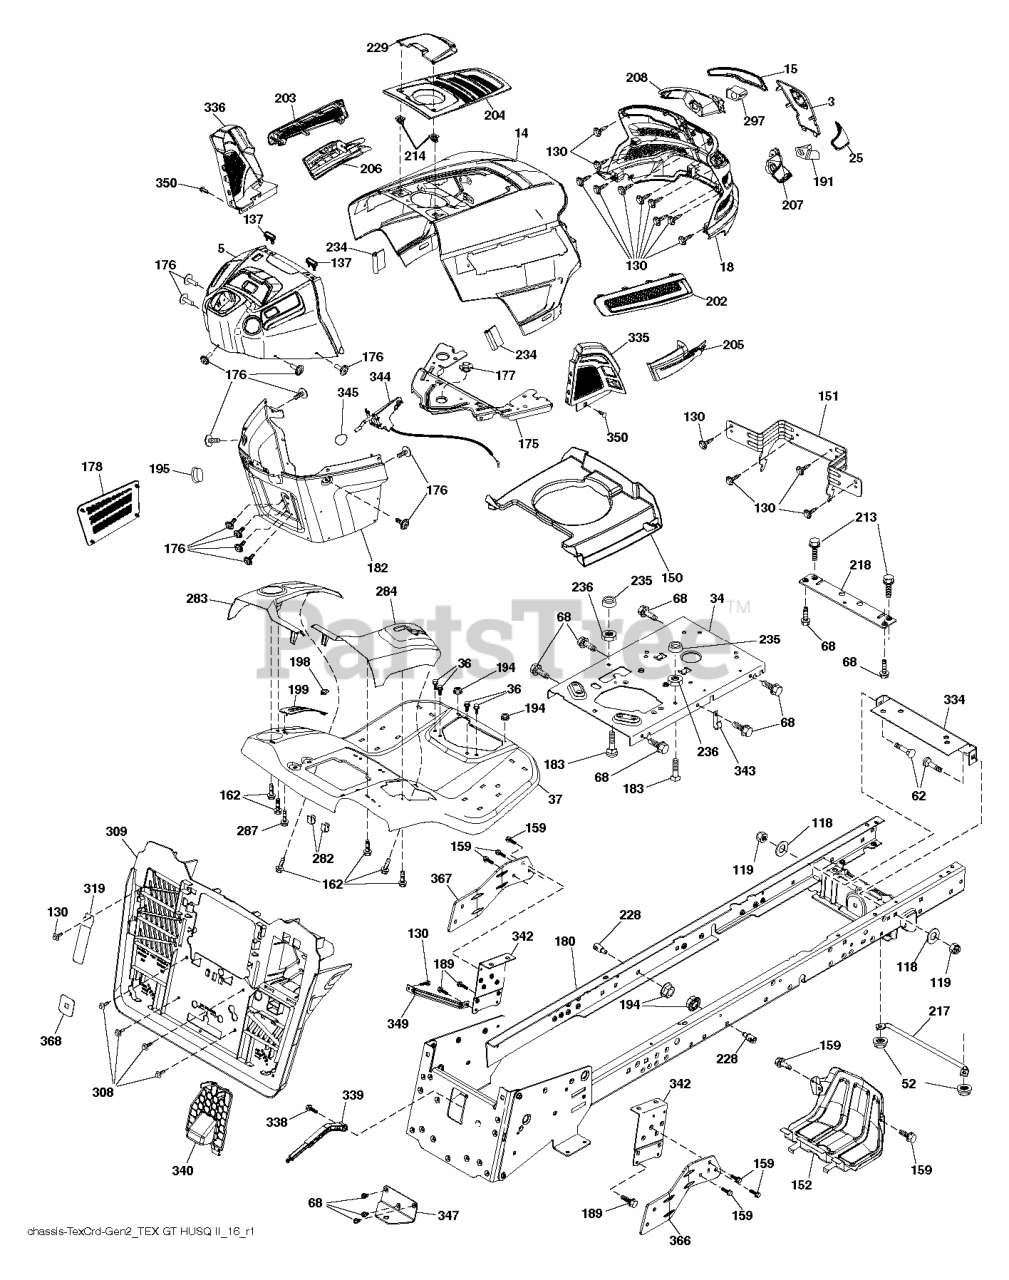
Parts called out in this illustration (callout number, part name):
3	APPLIQUE.SUBASM.GT.HUSQ.II
14	HOOD.ASM.HUSQVARNA.GT.TEX.ORAN
15	LENS.HEADLIGHT.LH.GTII.2011
18	GRILLE.SUBASM.GT.HUSQ.II
25	LENS.HEADLIGHT.RH.GTII.2011
34	PLATE.ENGINE.10GA.CRD.GENII
36	SCREW 5/16"
37	FENDER.TEX.SRD.CRD.FRN.GUARDS
52	LOCKNUT
62	BOLT D
68	SCREW LT
118	WASHER
130	SCREW.#10 X 0.750.BOS
137	BUMPER DASH
150	AIR.DUCT.GTV.BLACK
151	BRACKET.PIVOT.HOOD.GT.HUSQ.II
152	SHIELD.BROWNING.PNT.GT.V2
159	SCREW, 3/8-16X3/4
162	SCREW.HI-LO.CONSOLE
175	PLATE.CROSSMEMBER.HUSQ
176	SCREW.#10-24X5/8.RN.QU
177	BUSHING, STEERING
178	CARGO.ASM.NET.TXGT.W/C
180	WELDMENT.CHASSIS.TEX.CRD.GEN.2
182	DASH DASH LOWER
183	BOLT.5/16-18X1-1/4 FULL THD
189	SCREW
191	INSERT.REFLECTIVE.RH.HUSQ.GTII
194	NUT LOCK HEX FLANGE 5/16-18
195	PLUG.HOLE.DASH.LOWER.12V.BLK
198	INDICATOR.DECK.LIFT.RED
199	PLATE DECK LIFT
202	VENT.SIDE.RH.GT.HUSQ.II.
203	VENT.SIDE.LH.GT.HUSQ.II.498
204	VENT.TOP.EXTERNAL.FILL.GT2.GRE
205	SIDE.TRIM.RH.GT.HUSQ.II
206	SIDE.TRIM.LH.GT.HUSQ.II.GRAY
207	BEZEL LIGHT.RH.GT.II.MYLAR
208	BEZEL LIGHT.LH.GT.II.MYLAR
213	BOLT
214	CLIP.RETAINER.TINNER.
217	ROD.PIVOT.HOOD
218	X-PIECE.HOOD.STOP.NON/
228	STUD.FASTNER.W/ANTI-ROTATE
229	LID.EXT.FILL.GT.HUSQ2.BLACK
234	BUMPER.HOOD.TEX.HUSQVARNA
235	SPACER FENDER
236	NUT.CENTERLOCK.5/16-
282	CLIP.RETAINER.CONSOLE.LT.HUSQ
283	CONSOLE.DECKLIFT.CRDII.498
287	SCREW 1/4X20
297	INSERT.REFLECTIVE.LH.HUSQ.GTII
308	BOLT.5/16-18UNCX3/4 W/SEMS.BLK
309	BACKPLATE.ASM.CRDII.ANTIROTAT
319	LEVER.BAG.CRDII.ANTIROTATION
334	BRACKET.ENGINE
335	COVER-LH.LOWER.DASH.GT2.BLACK
336	COVER.LOWER.DASH.RH.BLACK
338	BOLT BOLT SHOULDER
339	LEVER LEVER BAGGER
340	BATTERY.DOOR.TEX.CRD.GEN.2,1
342	SUPPORT SUPPORT FENDER
343	CLIP CLIP
344	CONTROL.EZ.MULCH.TEX/CRD
345	RP KNOB.OVAL.TAPERED.3/8-16BLK
347	HITCH HITCH TOW TEX CRD GEN 2
349	BRACKET.SUPPORT.LRVB/CRD
350	CLIP.X-MAS.TREE
366	BRACKET.RH.FRONT.BAGGER.BLACK
367	BRACKET.LH.FRONT.BAGGER.BLACK
368	FULL.LEVER.BAGGER.TEX.CRD
